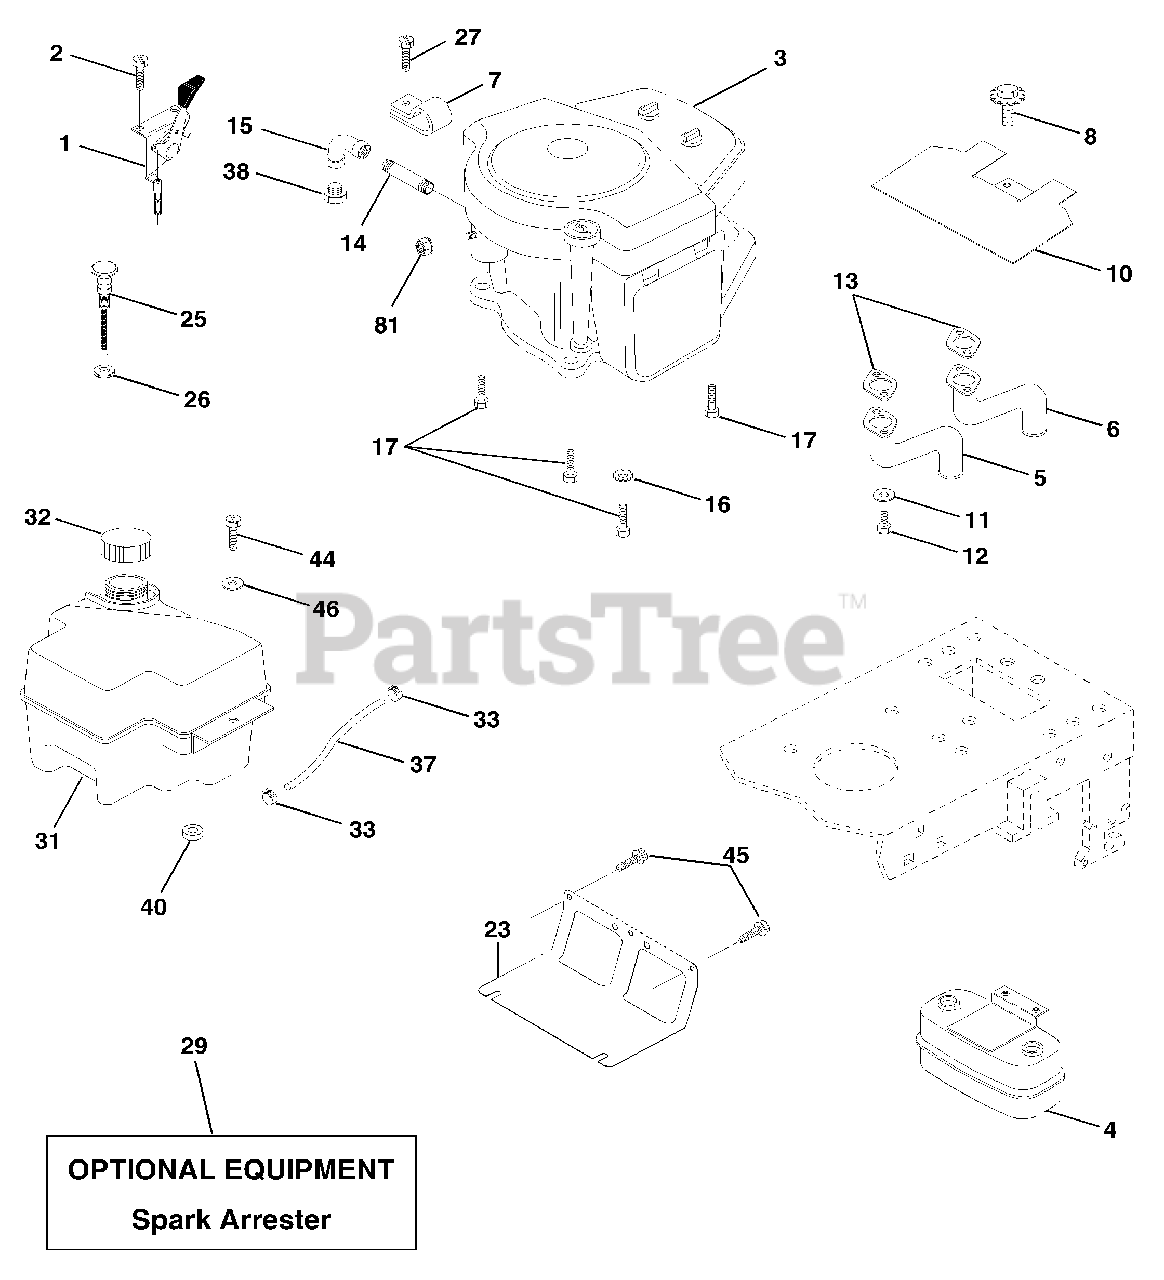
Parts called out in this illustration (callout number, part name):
1	Control Th LH Flag 35.5
2	Screw Hex Thd Cut 1/4-20x5/8 T
4	Muffler Exhaust
5	Exhaust Asm. Left
6	Exhaust Asm Right
7	Clamp Tube Double Engine
8	Bolt 5/16-18 UNC x 3/4 W/Sems
10	Heat Shield LT
11	Washer Lock Hvy. Helical 1/4
12	Bolt Fin Hex 1/4-20 x 3/4
13	Gasket Muffler
14	Nipple Pipe 3/8 Npt X 3"
15	Elbow Std 90 Degree 3/8-18 Npt
16	Washer Lock Ext Tooth 3/8
17	Screw Thdrol 3/8-16 x 1-1/2 Tytt
23	Shield Browning/Debris Guard
25	Control Choke
26	Nut Keps 3/8-24 UNF
27	Screw TT Flange
29	Kit Spark Arrestor (Flat Scrn)
31	Tank Fuel Front
32	Cap Asm Fuel
33	Clamp Hose
37	Line Fuel
38	Oil Drain Plug
40	Bushing Snap Nyl Blk Fuel Line
44	Screw Hexwsh Thdrol 1/4-20 x 3/4
45	Screw Hex Wsh Thdrol 3/8-16 x 3/4
46	Washer 9/32 x 7/8 x 16 Ga.
81	Nut Keps Hex 1/4-20 Unc
